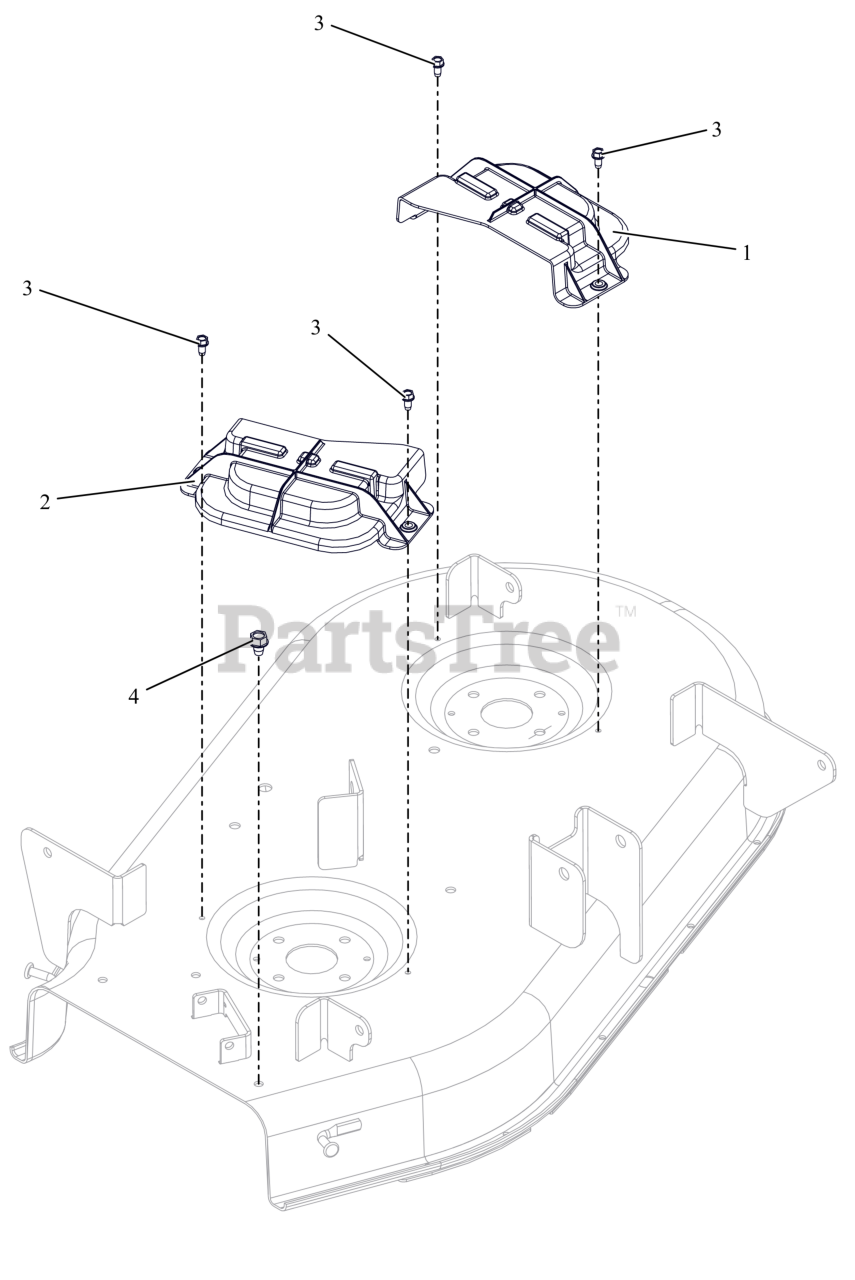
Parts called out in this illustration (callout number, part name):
1	COVER-BELT, MOLDED
2	COVER-BELT, MOLDED
3	SCR-TAP .25-20X.50 HWH ZCC
4	SCR,TAP .375-16X.50 HWH TR ZCC
